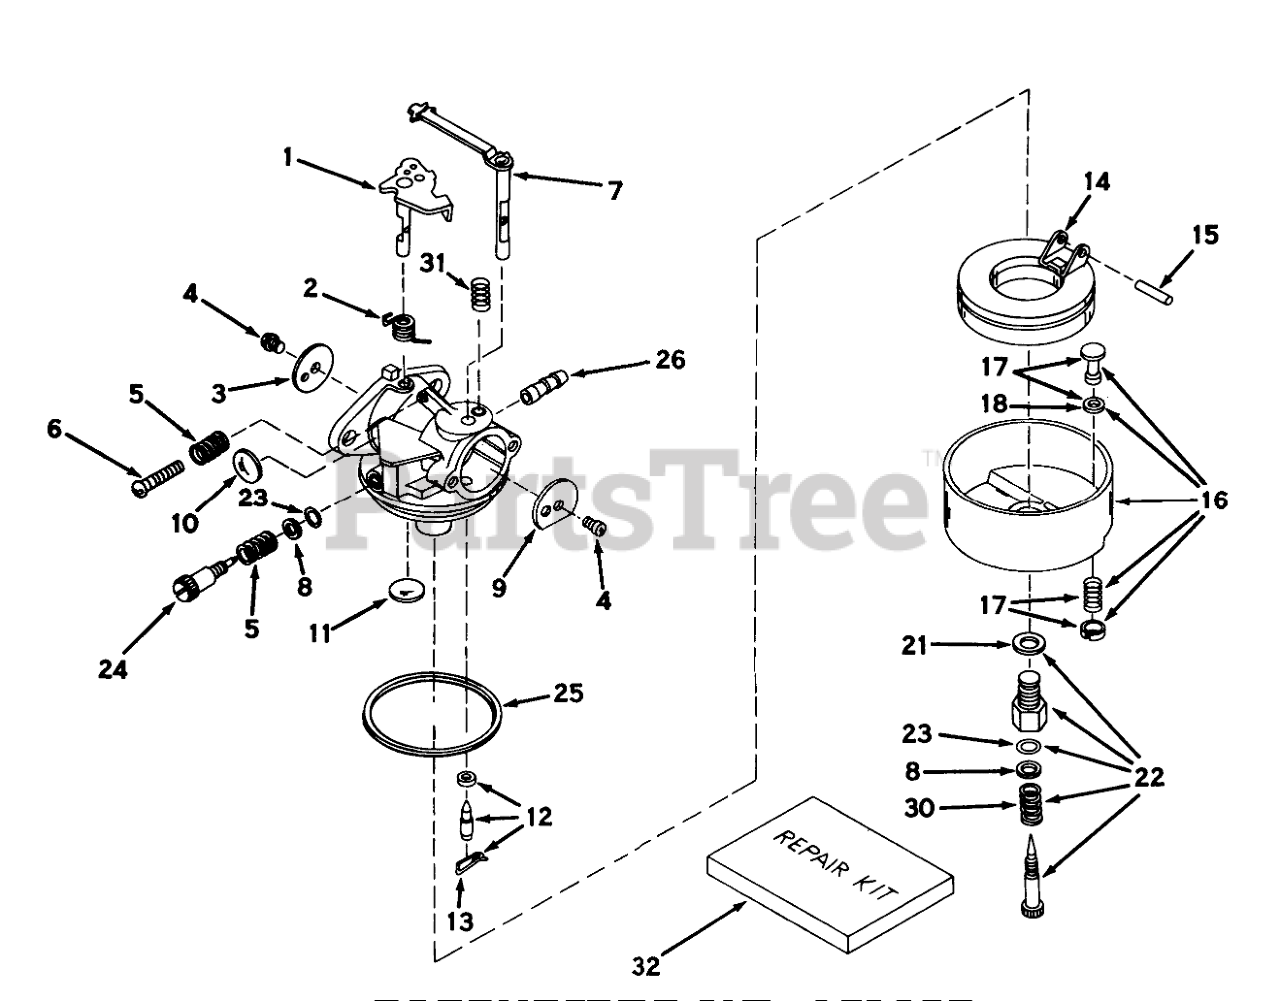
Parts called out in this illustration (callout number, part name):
1	Shaft/Lever-Throttle
2	Spring, Return
3	Shutter-Throttle
4	Screw-Shutter
5	Spring-Tension
6	Screw-Throttle Crack Screw / Idle Speed
7	Shaft & Lever Ass-y Choke
9	Shutter-Choke
10	Plug-Welch, Idle Mixture Well
11	Plug-Welch, Atmospheric Vent
12	Inlet Needle, Seat & Clip Assy. (Incl. No. 13)
13	Clip-Spring
14	Float,Carburetor
15	Shaft-Float
16	Bowl & Drain Assy., Float (Incl. No. 17)
17	Plunger Assy., Drain (Incl. No. 18)
18	Gasket-Plunger, Drain
21	Washer-Bowl Nut
22	Adjustment Screw Assy., Main (Incl. Nos. 8, 21, 23 & 30)
23	"O"Ring
24	Screw, Idle Adj.
25	O Ring-Bowl, Float
26	Fitting, Fuel Inlet
31	Spring-Positioning, Choke
32	Kit-Repair
